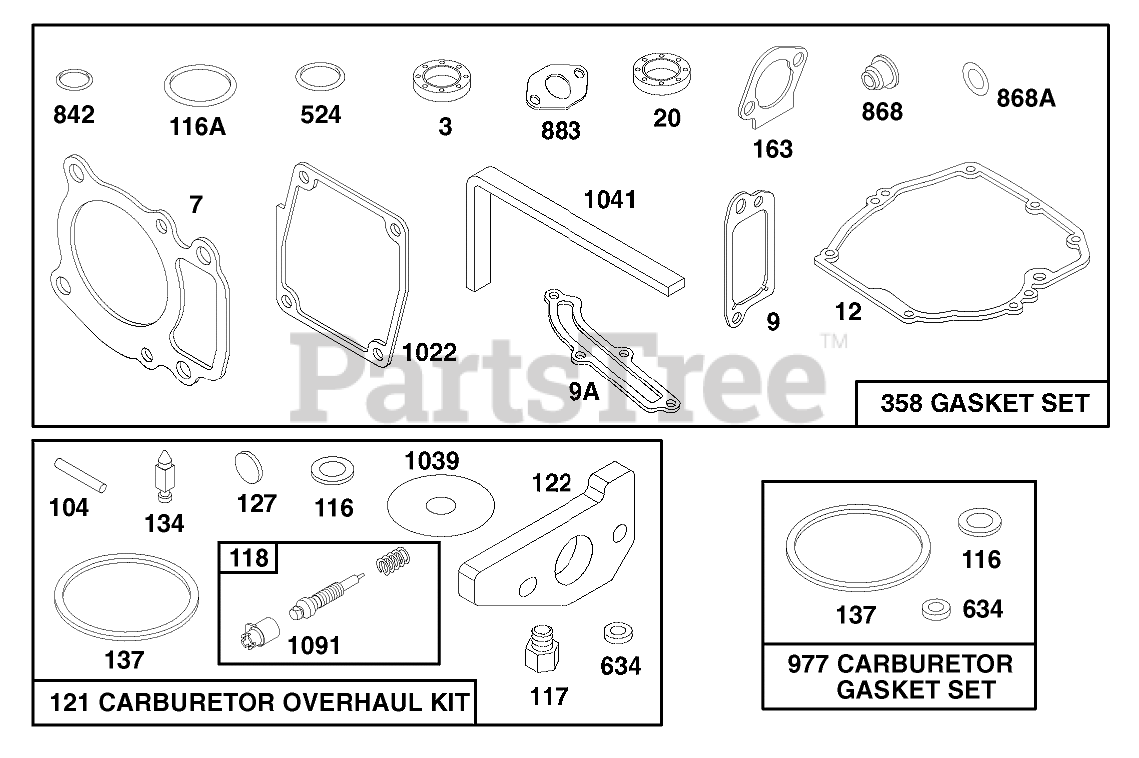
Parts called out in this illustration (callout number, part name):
3	SEAL - OIL
7	CYLINDER HEAD GASKET
9	BREATHER GASKET
9A	GASKET-BREATHER
12	ENGINE BASE GASKET
20	SEAL-OIL
104	FLOAT HINGE PIN
116	SEALING GASKET
116A	O RING SEAL
117	Jet-Main
118	VALVE/SPRING - NEEDLE
121	KIT-CARBURETOR OVERHAUL
122	ADAPTER ASSEMBLY
127	PLUG - WELCH
134	Valve-Inlet (Includes Seat)
137	FLOAT BOWL GASKET
163	AIR CLEANER GASKET
358	GASKET SET
524	O-RING
634	SEAL WASHER
842	O-RING
868	SealAssy-Valve
868A	Seal-Valve
883	EXHAUST GASKET
977	CARBURATOR GASKET SET
1022	ROCKER COVER GASKET
1039	FLOAT LIMITER
1041	SEAL - FOAM
1091	CAP - LIMITER
